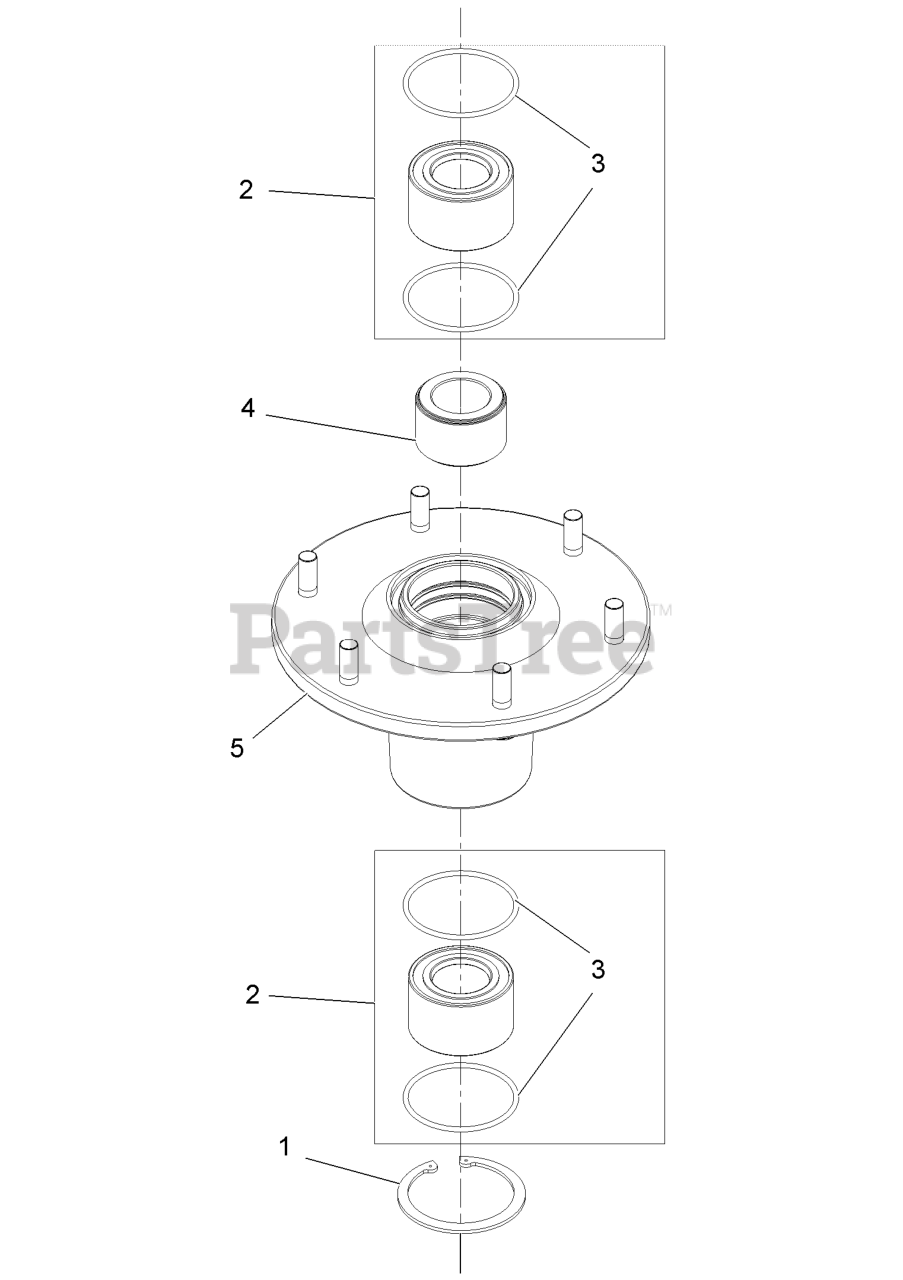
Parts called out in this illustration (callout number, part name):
1	Ring-Retaining
2	Asm, Bearing W/O-Rings
4	Spacer, Bearing
5	Asm, Housing W/Studs
